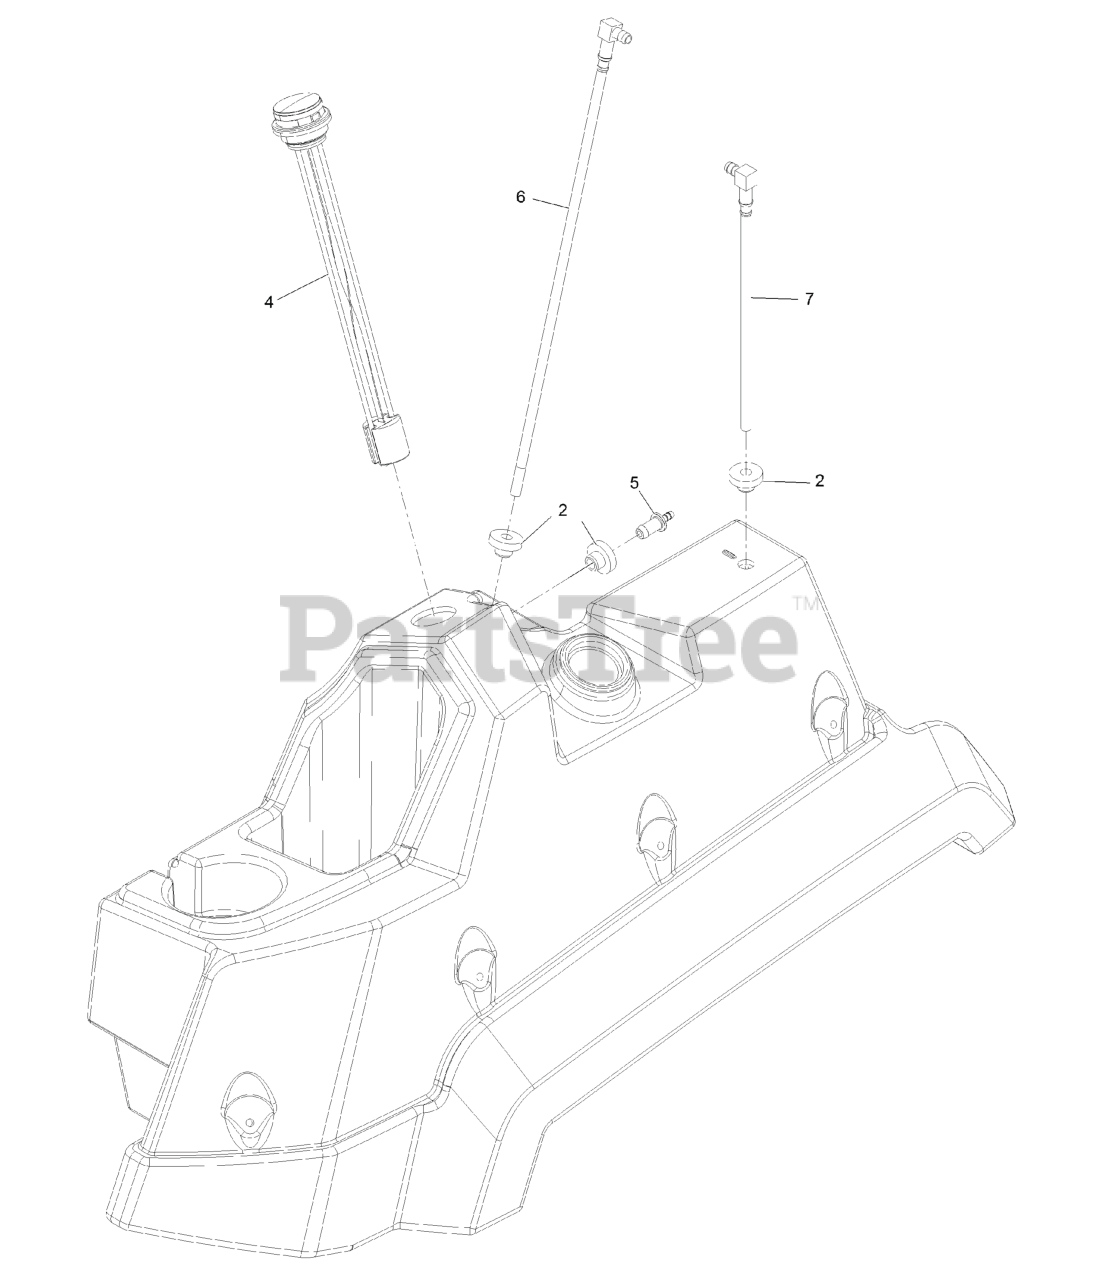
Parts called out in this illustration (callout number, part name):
2	BUSHING
4	GAUGE-FUEL
5	FITTING-ORIFICE, STRAIGHT
6	PICK-UP-FUEL
7	RETURN-FUEL
